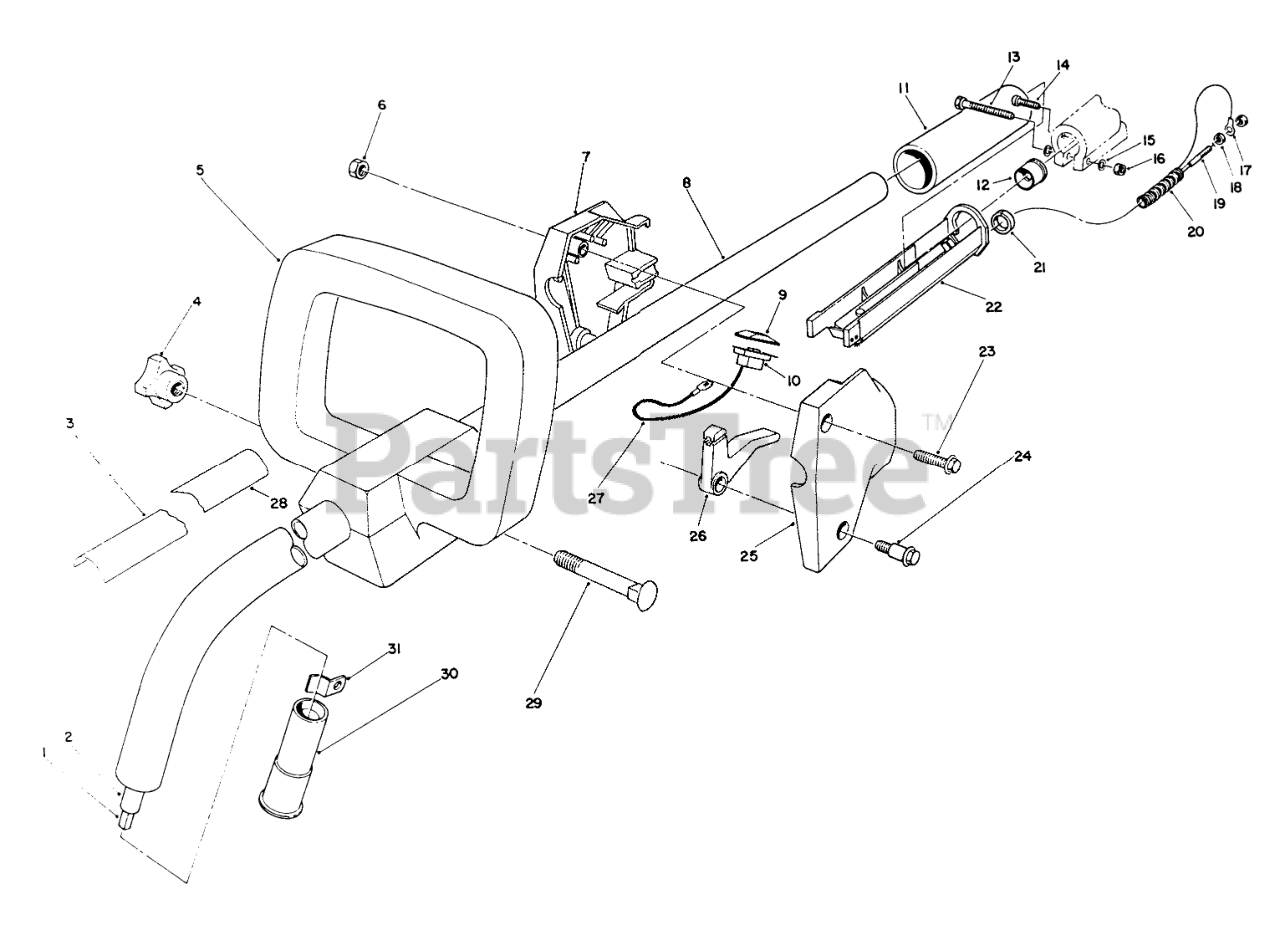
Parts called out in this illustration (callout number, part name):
1	FLEX SHAFT
2	FLEX SHAFT CASING ASM
3	DECAL - TC 1800
4	Knob
5	SECONDARY HANDLE
6	NUT-LOCK, NI
7	RH HOUSING
8	Tube-Curved
9	SWITCH COVER
10	SWITCH
11	GRIP-RUBBER
12	BUSHING
13	Screw-Engine Clamp
14	Screw-Jams
15	Washer-Flat
16	Nut-Engine Clamp
17	WIRE ASSEMBLY
18	NUT-JAM
19	THROTTLE CABLE
20	CABLE COVER
22	TROUGH
24	SCREW-SHOULDER
25	LH HOUSING
26	THROTTLE LEVER
27	WIRE ASM
28	Decal
29	BOLT-CARRIAGE
30	INSERT-POLE END
31	LOWER TUBE RETAINER
